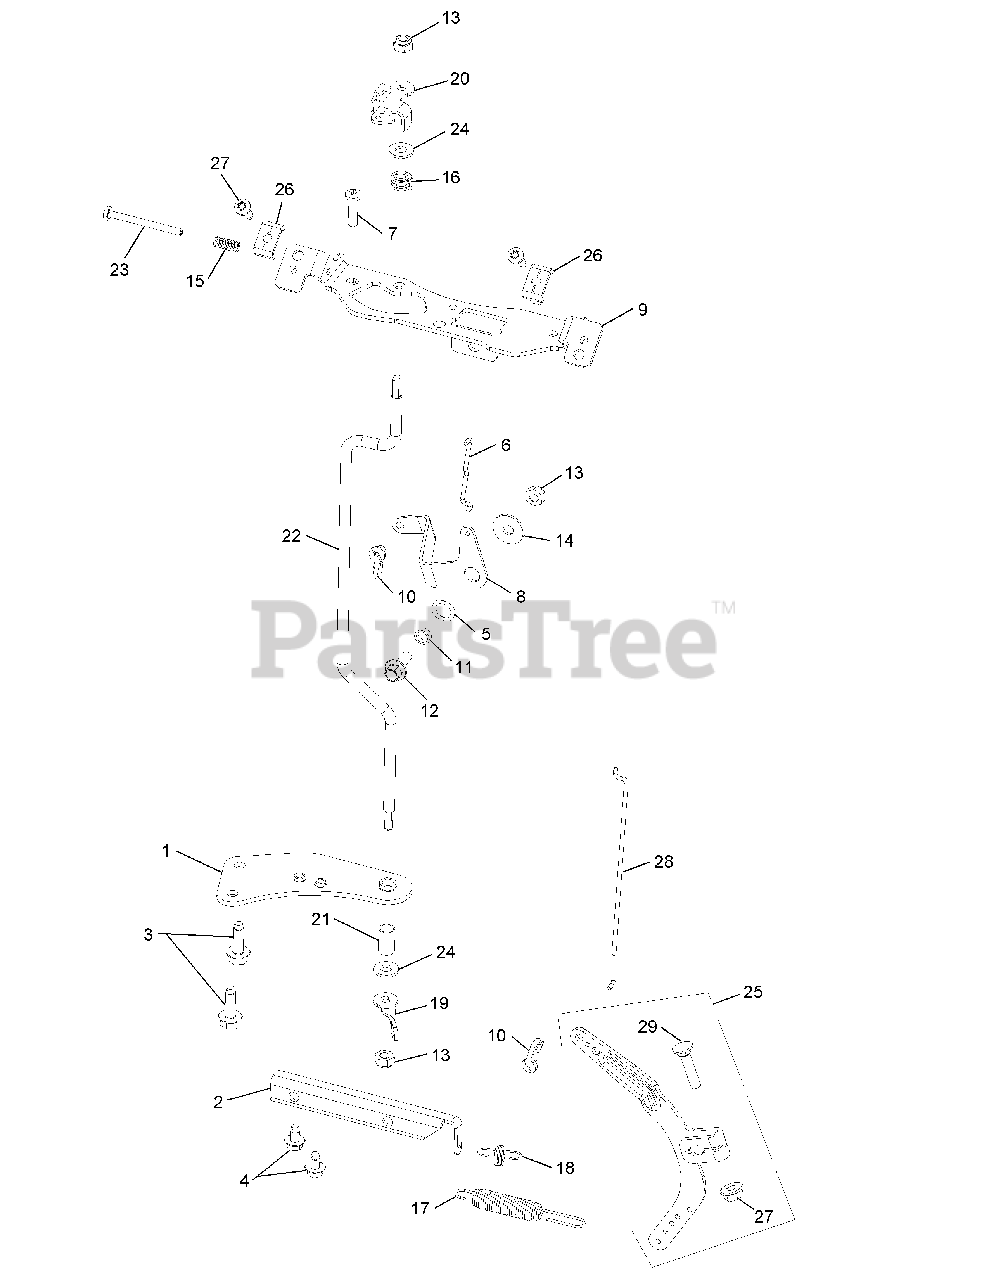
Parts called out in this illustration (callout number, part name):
1	Throttle Shaft Bracket
2	Governed Idle Bracket
3	Thread Forming Screw
4	Thread Forming Screw
5	Spring Washer, 3/8
6	Choke Linkage
7	Screw, 11-16 x 3/4
9	Control Bracket
10	Throttle Linkage Bushing
12	Flange Screw, M6 x 1.0 x 16
13	Lock Nut, M6 x 1.0
14	Flat Washer, 1/4
15	Speed Control Spring
16	Throttle Shaft Spring
17	Governor Spring
18	Governed Idle Spring
19	Throttle Control Lever
20	Throttle Control Lever
22	Control Shaft
23	Hex Head Screw
24	Flat Washer, 1/4
25	Governor Lever
27	Flange Nut, M6 x 1.0
28	Throttle Linkage
29	Bolt, M6 x 1.0 x 25
